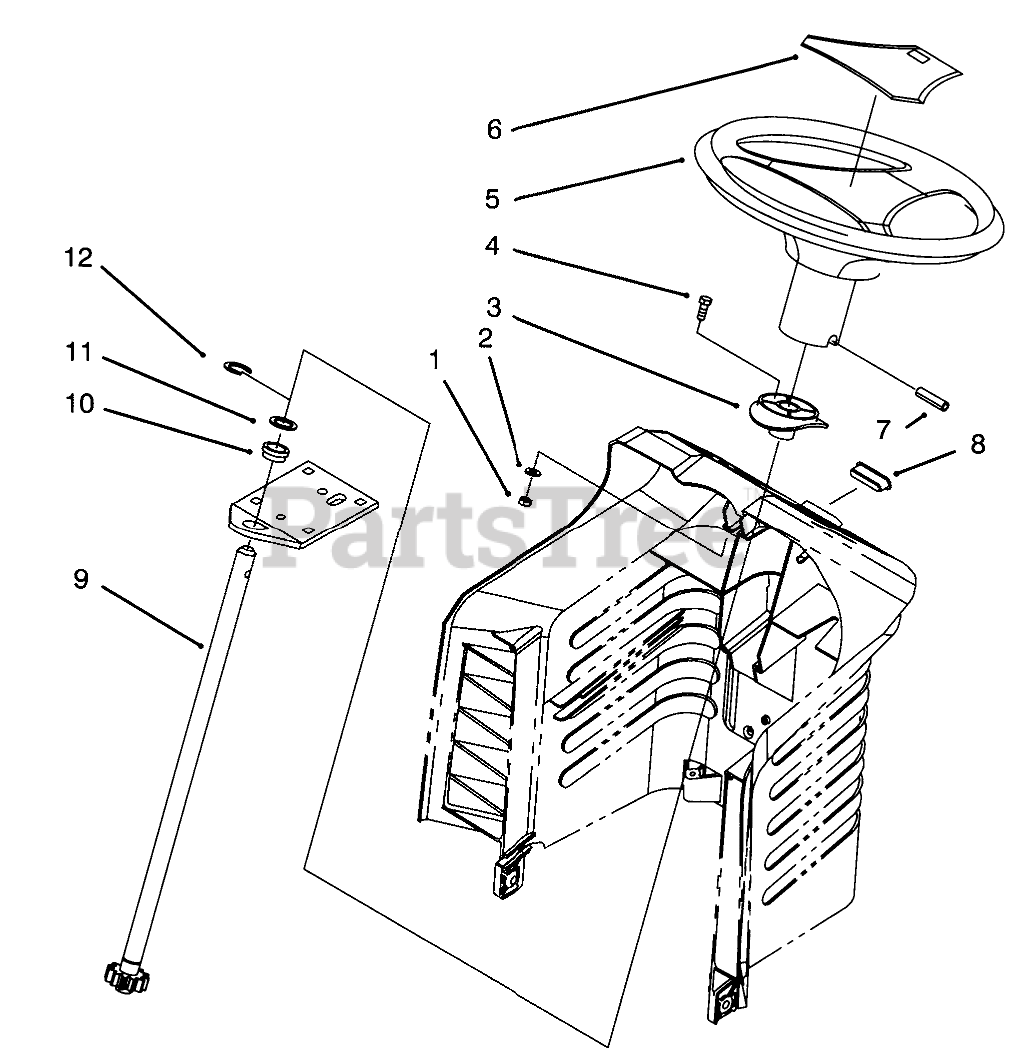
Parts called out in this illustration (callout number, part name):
1	NUT-LOCK, NI
2	WASHER-FLAT
3	BUSHING-SLIDING
4	SCREW-HH
5	Wheel-Steering (Incl. Ref. #6)
6	COVER-WHEEL
7	PIN-ROLL
9	SHAFT-STEERING, LONG
10	BEARING-FLANGE
11	WASHER-THRUST
12	E-RING
